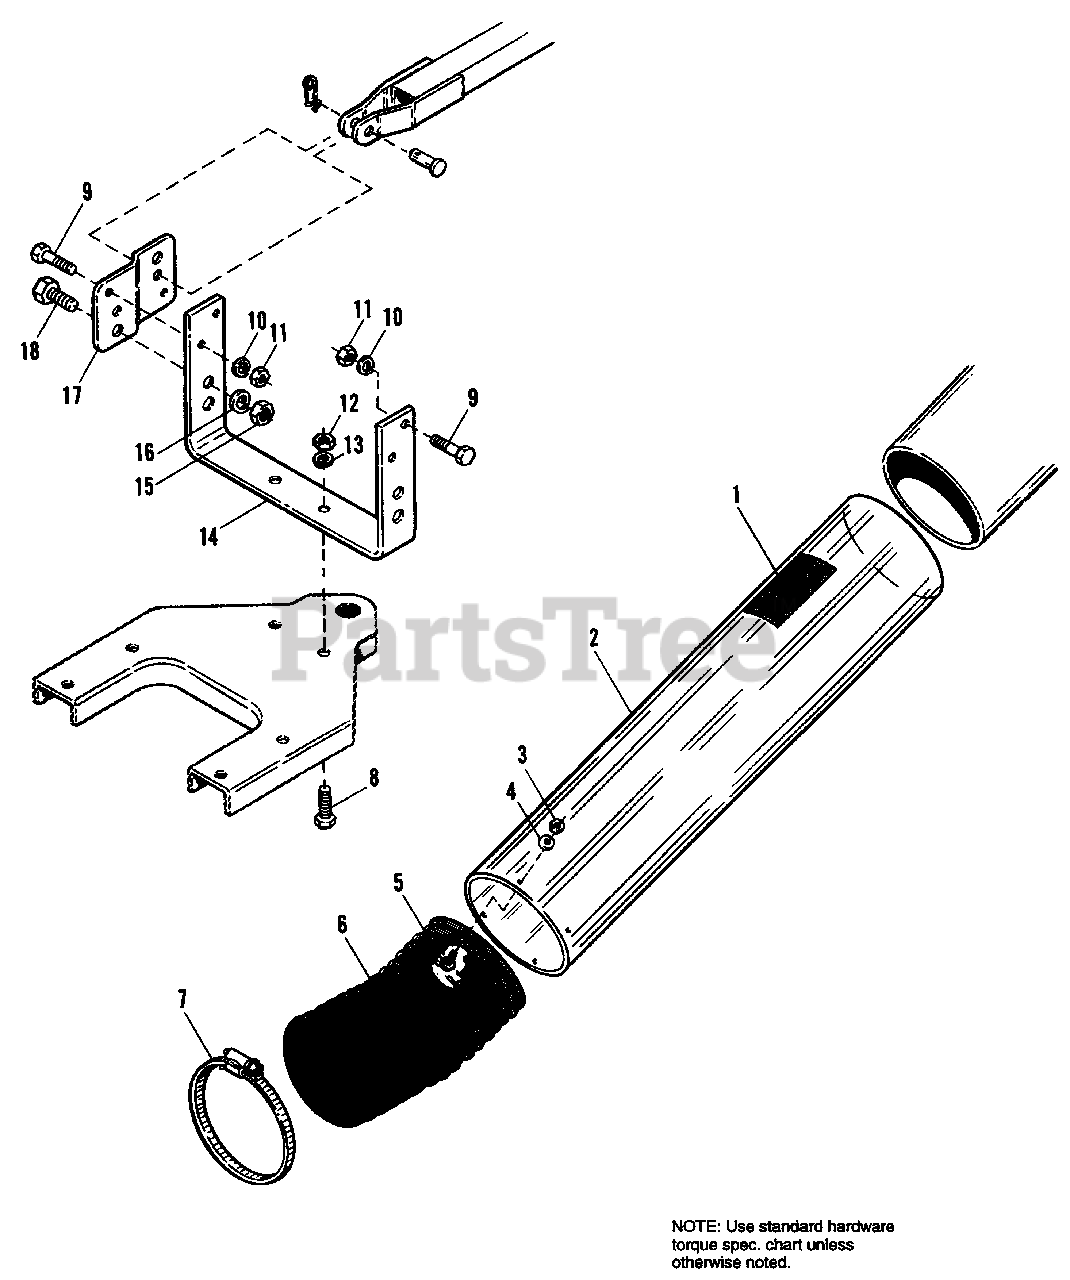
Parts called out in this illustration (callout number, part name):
1	DECAL, Cleaning Inst.
2	TUBE ASSY.
3	NUT, Hex, Full, Lock, #10-32
4	WASHER, Plain, #10
5	SCREW, Phillips, Truss Hd., #10-32 x 1/2
8	CAPSCREW, Hex, 1/2-13 x 1-1/4
9	CAPSCREW, Hex Hd., 7/16-14 x 1-1/2
10	LOCKWASHER, 7/16
11	NUT, Hex, Full, 7/16
12	NUT, Hex, Full, 1/2-13
13	LOCKWASHER, 1/2
14	BRACKET, Hitch
15	NUT, Hex, Full, 5/8
16	LOCKWASHER, 5/8
17	BRACKET, Hitch
18	CAPSCREW, Hex Hd., 5/8-11 x 1-1/4
